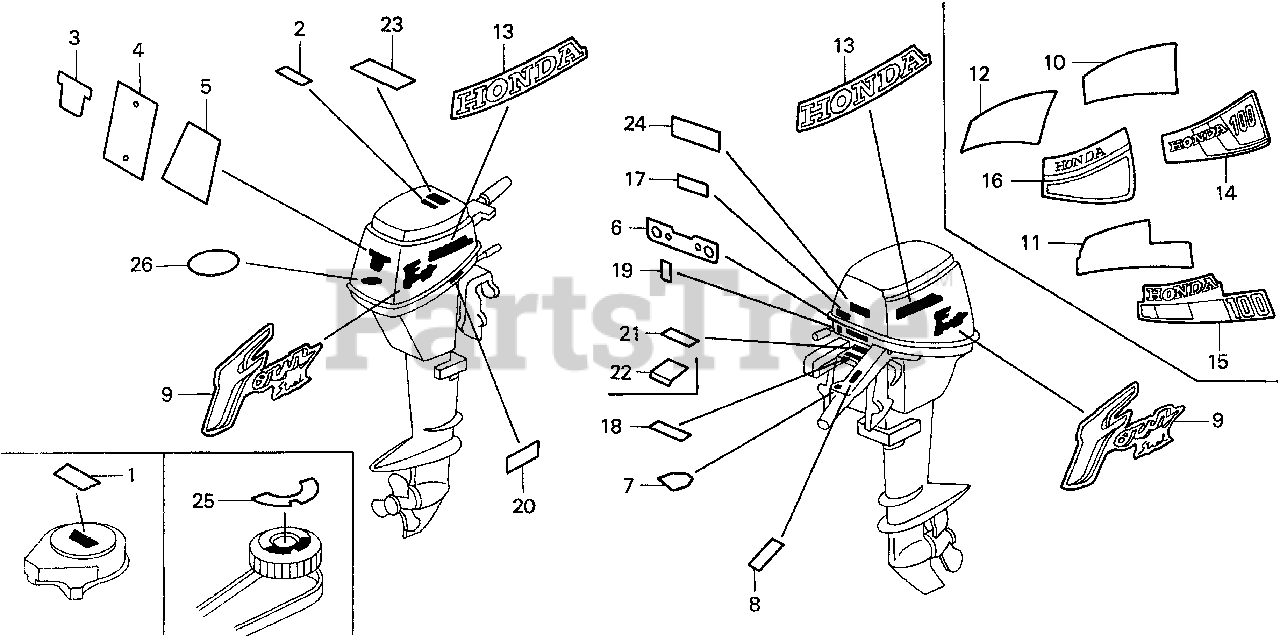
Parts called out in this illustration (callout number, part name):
1	MARK, RECOIL STARTER CAUTION
3	MARK, RR.
6	LABEL, INDICATION (E)
7	MARK, EMERGENCY SWITCH INDICATION (ENGLISH)
8	MARK, SPARE CLIP (ENGLISH)
9	MARK, SIDE
13	MARK, SIDE STRIPE
18	LABEL, SPECIFICATION
19	MARK, CHANGE
20	LABEL, CAUTION OIL (E)
21	LABEL, STORING CAUTION (ENGLISH)
23	LABEL, CAUTION OPERATOR (ENGLISH)
25	MARK, POINT
26	MARK, ENVIRONMENT (EPA 2006)
